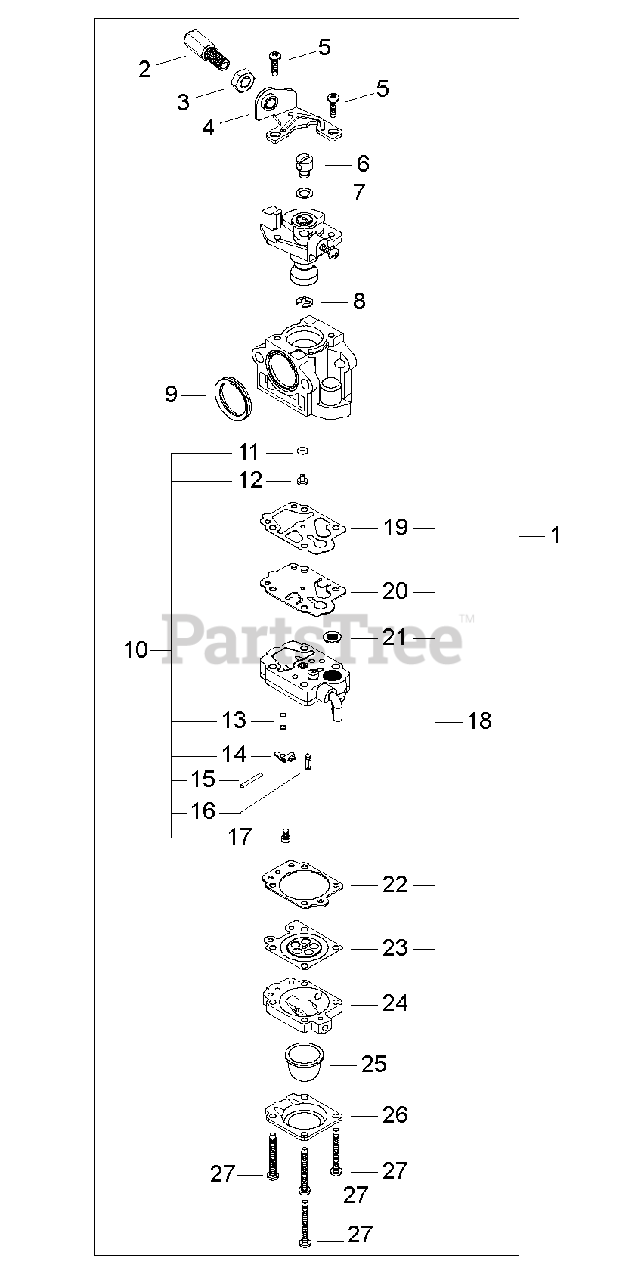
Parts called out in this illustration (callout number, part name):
1	CARBURETOR
2	NUT, CABLE ADJUST
3	NUT
4	BRACKET, CABLE
5	SCREW
6	SWIVEL
7	WASHER
8	RING, RETAINING
9	SEAL
10	INLET NEEDLE VALVE KIT
11	O-RING
12	JET
13	SPRING, METERING LEVER
14	LEVER, METERING
15	PIN, METERING LEVER
16	VALVE, INLET NEEDLE
17	SCREW, METERING LEVER PIN
18	DIAPHRAGM/GASKET KIT
19	GASKET, PUMP
20	DIAPHRAGM, PUMP
21	STRAINER
22	GASKET, METERING
23	DIAPHRAGM, METERING
24	BASE, PURGE
25	BULB, PURGE
26	RETAINER, PURGE BULB
27	SCREW, PUMP COVER
